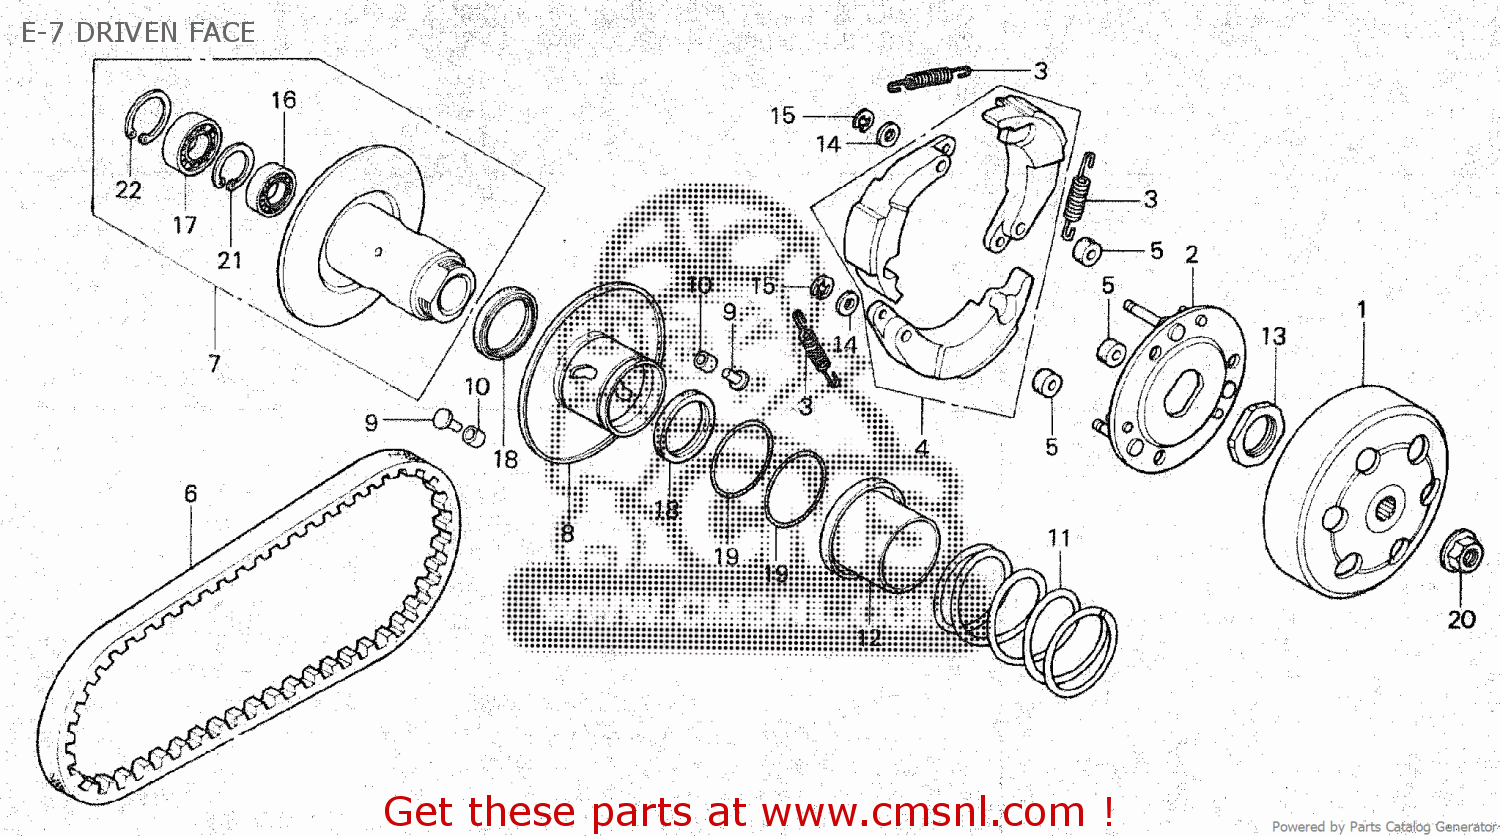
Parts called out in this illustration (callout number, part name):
1	CLUTCH OUTER COMP
2	PLATE COMP,DRIVE
3	SPRING,CLUTCH
4	WEIGHT SET,CLUTCH
5	RUBBER,CLUTCH DPR
6	BELT,DRIVE
7	FACE ASSY.,DRIVEN
8	FACE,MOVABLE DRIV
9	PIN,ROLLER GUIDE
10	ROLLER,GUIDE
11	SPG.,DRIVEN FACE
12	COLLAR,SEAL
13	NUT SPECIAL 28MM
14	WASHER,THRUST,8MM
15	CIR CLIP,7MM
16	B/BRG,RAD,N/COM
17	B/BRG,RAD,N/COM
18	SEAL,DRIVEN FACE
19	O RING PINION CAP
21	CIRCLIP,IN,24
22	CIRCLIP IN 28MM
